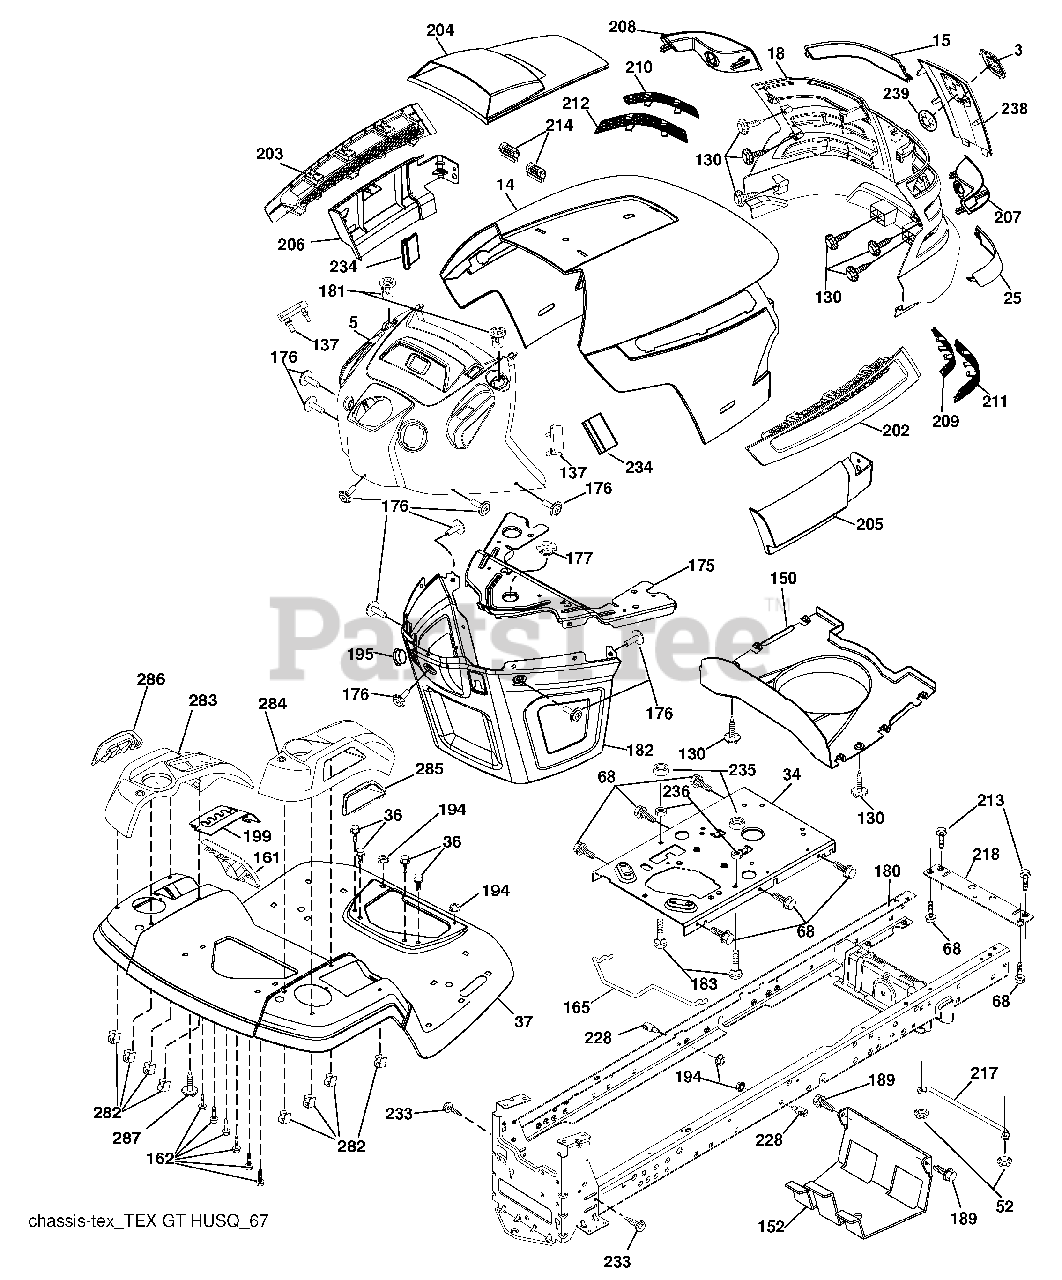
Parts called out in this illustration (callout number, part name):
3	Logo
14	Hood
18	Grille Asm.
34	Plate Engine
36	Screw 5/16-18 x 3/4
52	Nut Lock 5/16-18
68	Screw 5/16-18 x 1/2
130	Screw #10 x 0.750 BOS Thread
137	Bumper Dash
152	Shield Browning
161	Window Fuel
165	Support Tank Rear
175	Crossmember
176	Screw 10-24 x 5/8
177	Bushing Steering
178	Cargo Net Asm.
180	Chassis
181	Bushing Mtg. Fender Crgo
182	Dash Lower
183	Bolt 5/16-18 unc x 1-1/4
189	Screw 5/16-18 x 3/4
194	Nut Lock Hex Flange 5/16-18
195	Plug Hole Dash Lower
199	Plate Deck Lift
202	Vent Side Hood RH
203	Vent Side Hood LH
204	Vent Top Hood
205	Skirt Hood Side RH
206	Skirt Hood Side LH
209	Insert Hex Top RH
210	Insert Hex Top LH
211	Insert Hex Bottom RH
212	Insert Hex Bottom LH
213	Bolt 5/16-18 unc x 3/4
214	Clip Retainer Tinner
218	X-Piece Hood Stop
228	Stud Fastner
233	Bolt Shoulder
234	Bumper Hood
235	Spacer Fender
236	Nut Lock 5/16-18 unc
282	Clip Retainer Console
283	Console Deck Lift
284	Console Asm. Pedal Control
285	Console Insert RH
286	Console Insert LH
287	Screw Hex Washead 1/4-20 x 3/8
